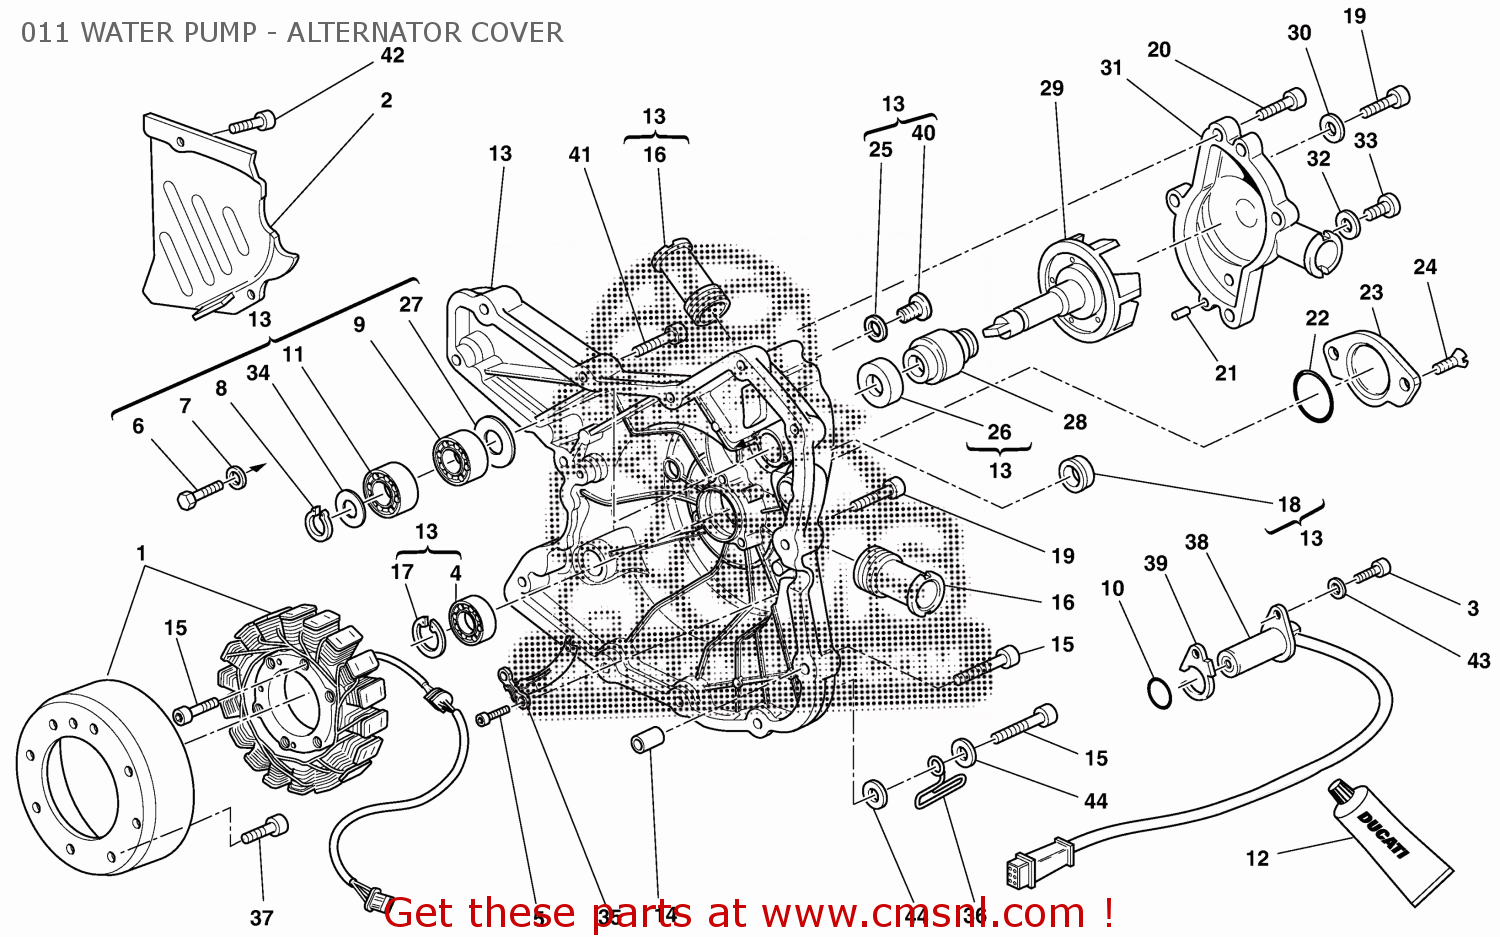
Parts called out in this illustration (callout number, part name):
1	FLYWHEEL
2	CHAIN PINION COVER
3	SCREW TCEI M6X16
4	BALL BEARING 6003 TN9 C3
5	SCREW TCEI M6X14
6	SCREW TE M6X16
7	WASHER 6X14.2X1.3
8	CIRCLIP
9	BEARING
10	O-RING
11	BALL BEARING 6000
12	LIQUID GASKET
13	GENERATOR COVER
14	PIN DOWEL
15	SCREW TCEI M6X30
16	WATER PUMP DELIVERY PIPE UNION
17	CIRCLIP
18	OIL SEAL
19	SCREW TCEI M6X25
20	SCREW TCEI M6X18
21	PIN DOWEL
22	O-RING
23	COVER
24	SCREW TSPEI M6X14
25	ALUMINIUM GASKET
26	MECHANICAL SEAL
27	SPACER
28	MECHANICAL SEAL
29	WATER PUMP ROTOR
30	GASKET
31	WATER PUMP COVER
32	WASHER 10X14X1
33	PLUG
34	WASHER 10X17X1.8
35	CABLE GUIDE
36	GUIDE, CABLE
37	SCREW TCCE M6X25
38	SENSOR, TIMING & RPM
39	GASKET, SENSOR 0.6 MM
40	THREADED PLUG M15X1
41	SCREW TCEI M6X16
42	SCREW TCEI M6X16
43	SPRING WASHER 6 MM
44	WASHER
